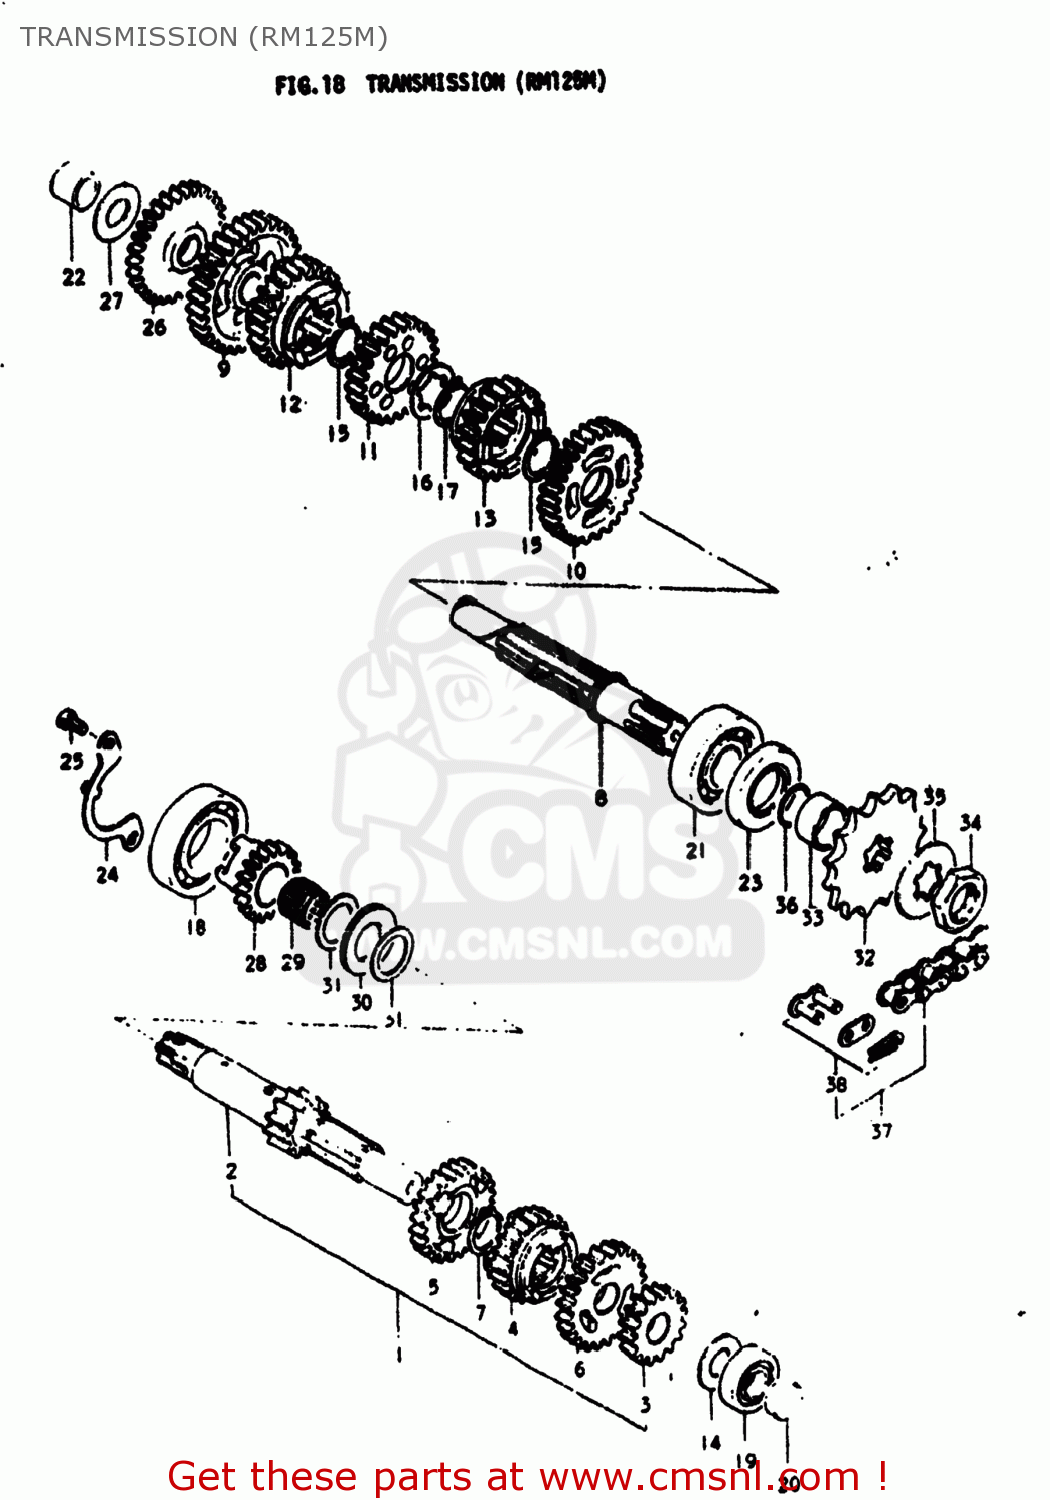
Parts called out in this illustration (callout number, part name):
1	SHAFT,COUNTER
2	SHAFT,COUNTER
3	GEAR,SECOND DRIVE
4	GEAR,THIRD DRIVE
5	GEAR,FOURTH DRIVE
6	GEAR,FIFTH DRIVE
7	CIRCLIP
8	SHAFT,DRIVE
9	GEAR,FIRST DRIVEN
10	GEAR,SECOND DRIVEN
11	GEAR,THIRD DRIVEN
12	GEAR,FOURTH DRIVEN
13	GEAR,FIFTH DRIVEN
14	WASHER
15	CIRCLIP
16	WASHER
17	CIRCLIP
18	BEARING, RH
19	BEARING
20	PLUG
21	BEARING
22	BUSH
23	OIL SEAL (25X44X7)
24	RETAINER,CNTR SHAFT BEARING
25	SCREW
26	GEAR,KICK STARTER IDLE
27	WASHER
28	GEAR,KICK STARTER DRIVE
29	BEARING(19.2X23.2X19)
30	BEARING(21X32X2.85)
31	WASHER(21X30X0.8)
32	SPROCKET,ENGINE
33	SPACER(20X25X12.5)
34	NUT
35	WASHER,LOCK
36	O RING(D:1,ID:19.5)
37	CHAIN ASSEMBLY,DRIVE
38	JOINT ASSEMBLY,CHAIN
